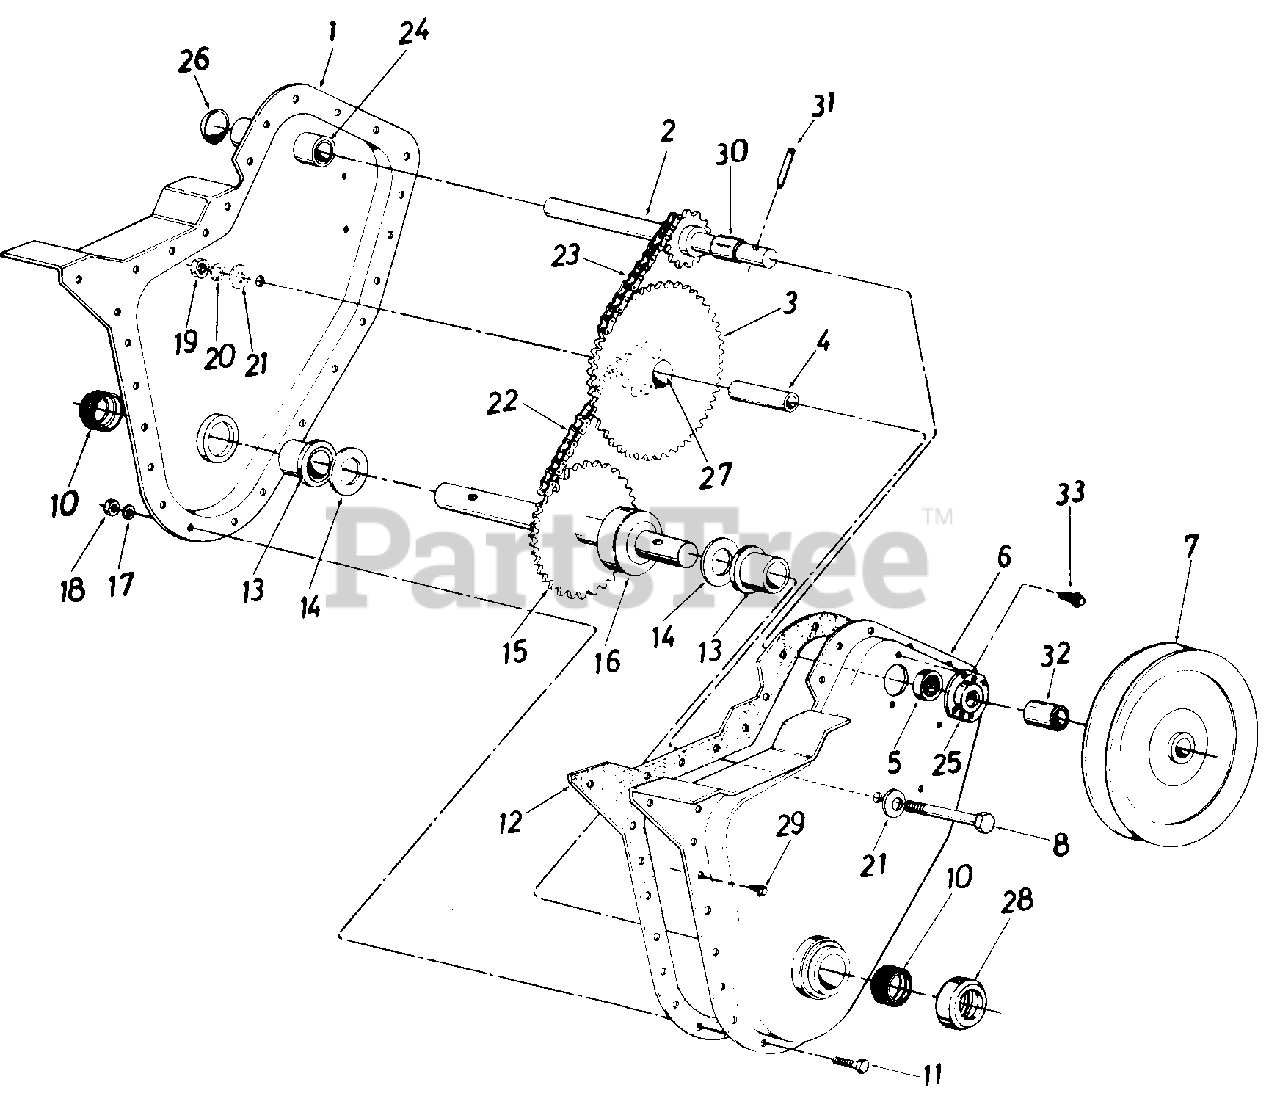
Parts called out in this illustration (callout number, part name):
1	Chain Case Ass'y.-R.H.
2	Input Shaft Ass'y.
3	Hub and Sprocket Ass'y.
4	Bearing Inner Race
5	Ball Bearing
6	Chain Case Ass'y.-L.H.
7	Pulley-Chain Case 51/2 x 1/2
8	Hex Bolt 3/8-24 x 2.50" Lg.
11	Hex Bolt 1/4-28 x .625" Lg.
12	Gasket
13	Flange Brg. .879 I.D.
14	Fl-Wash. .88 I.D. x 1.50 O.D. x .030
15	Tine Shaft Ass'y.
16	Spacer 718" I.D. x 2.0" O.D. x.68" Lg.
17	L-Wash. 1/4" I.D.
18	Hex Nut 1/4-28 Thd.
19	Hex Ins. L-Nut 3/8-24 Thd.
20	L-Wash. 3/8" I.D.
21	Bell-Wash. .406 I.D. x 1.130 O.D.
22	Chain #420-.50" Pitch x 38 Links
23	Chain #35-.375" Pitch x 50 Links
24	Bearing .62" I.D. x .813 O.D. x 1.31
25	Bearing Housing
26	Expansion Plug 13/16" Dia.
27	Bearing
28	Dust Cap
29	Hex Wash. Hd. Self-Tap Scr. 1/4-20 x .50" Lg.
30	Spacer.630" I.D. x .77" O.D. x.38" Lg.
31	Spring Pin Spiral 1/4" Dia. x 1-1/2" Lg.
32	Spacer .647 x 1.25"
33	Hex Wash. Hd. Self-Tap Scr. 1/4-20 x .38" Lg.
